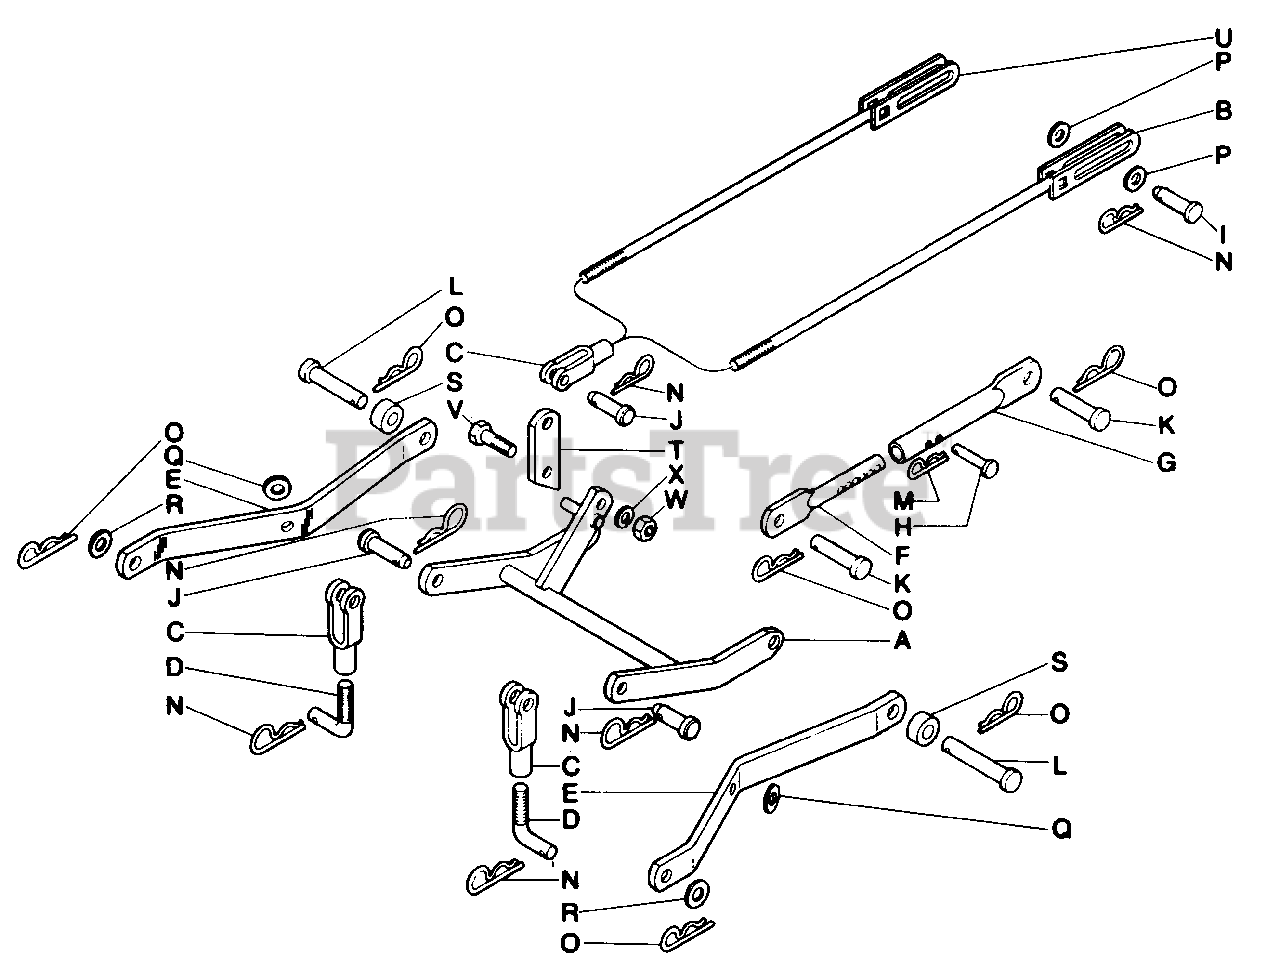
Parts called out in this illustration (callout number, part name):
A	Lift Frame Assembly
B	Lift Rod Assembly (Long)
C	Clevis
D	Pin-Lift Adjustment
E	Lift Link-Slide
F	Lift Link-Inside Half
G	Lift Link-Outside Half
H	Clevis Pin-1/4 Dia. x 1-1/2
I	Clevis Pin-7/16 Dia. x 1-3/4
J	Clevis Pin-1/2 Dia. x 1-3/4
K	Clevis Pin-5/8 Dia. x 2-1/4
L	Clevis Pin-5/8 Dia. x 3-1/2
M	Spring Clip
N	Spring Clip
O	Spring Clip
P	Washer, Flat 7/16 Plated
Q	Washer, Flat 1/2 Plated
R	Washer, Flat 5/8 Plated
S	Spacer (Gear Drive Tractors Only)
T	Lift Arm Extension
U	Lift Rod Assembly (Short)
V	Cap Screw, Hex Hd. 1/2-13 x 1-1/2 Plated Grade 5
W	Nut, Hex 1/2-13 Plated
X	Washer, Spring Lock 1/2 Plated
